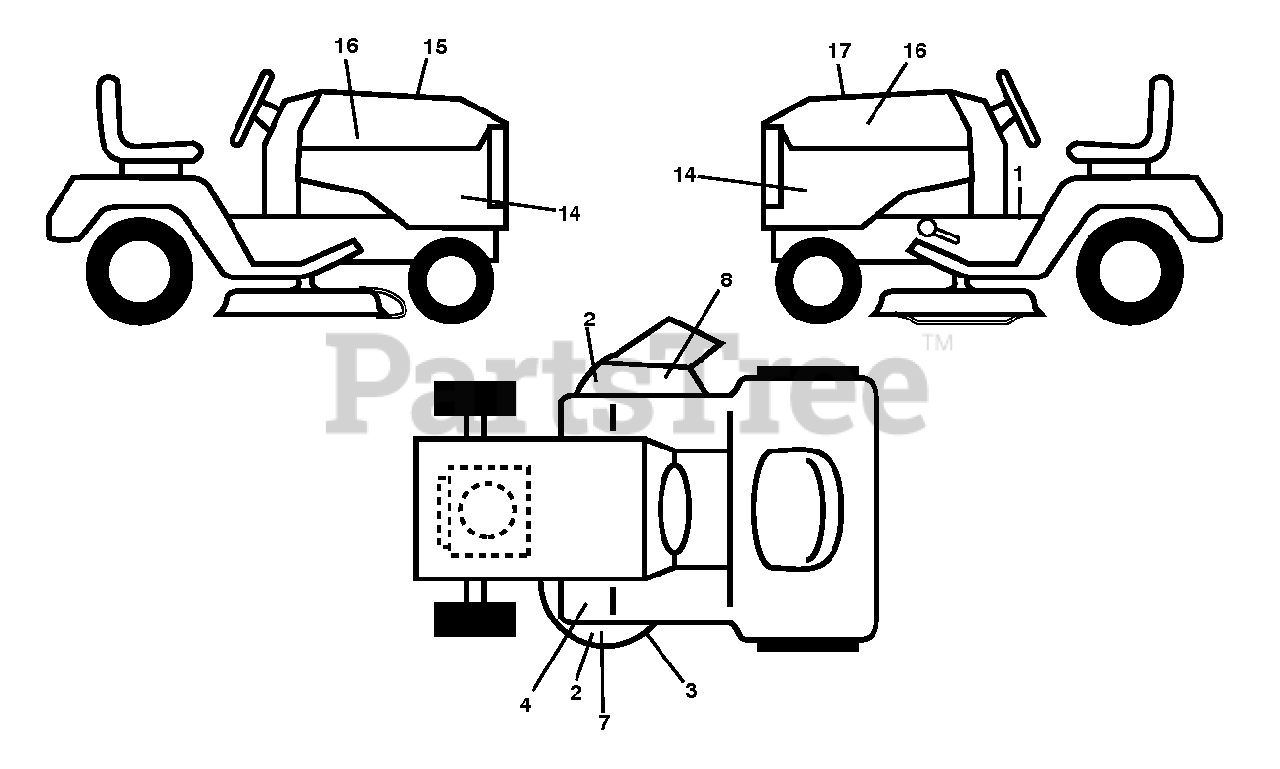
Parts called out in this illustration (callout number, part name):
1	DECAL.FENDER.WARNING.ENGLISH
2	DECAL.DECK.CLEARCUT.NOSTEP
3	Deck Decal, WA
4	DECAL BELT ROUTING DECAL DECAL
7	DECAL DECK DECAL DECAL.54DECK.
8	DECAL.TRACT/ZTR.DECKWARN.HUSQ
14	Tractor Side Panel Decal
15	DECAL.WARNING.CUST.RESP.E85.
16	DECAL.BADGE.170MM.TEXTLOGO.
17	DECAL G730.54F.KAW FR730.TGB
